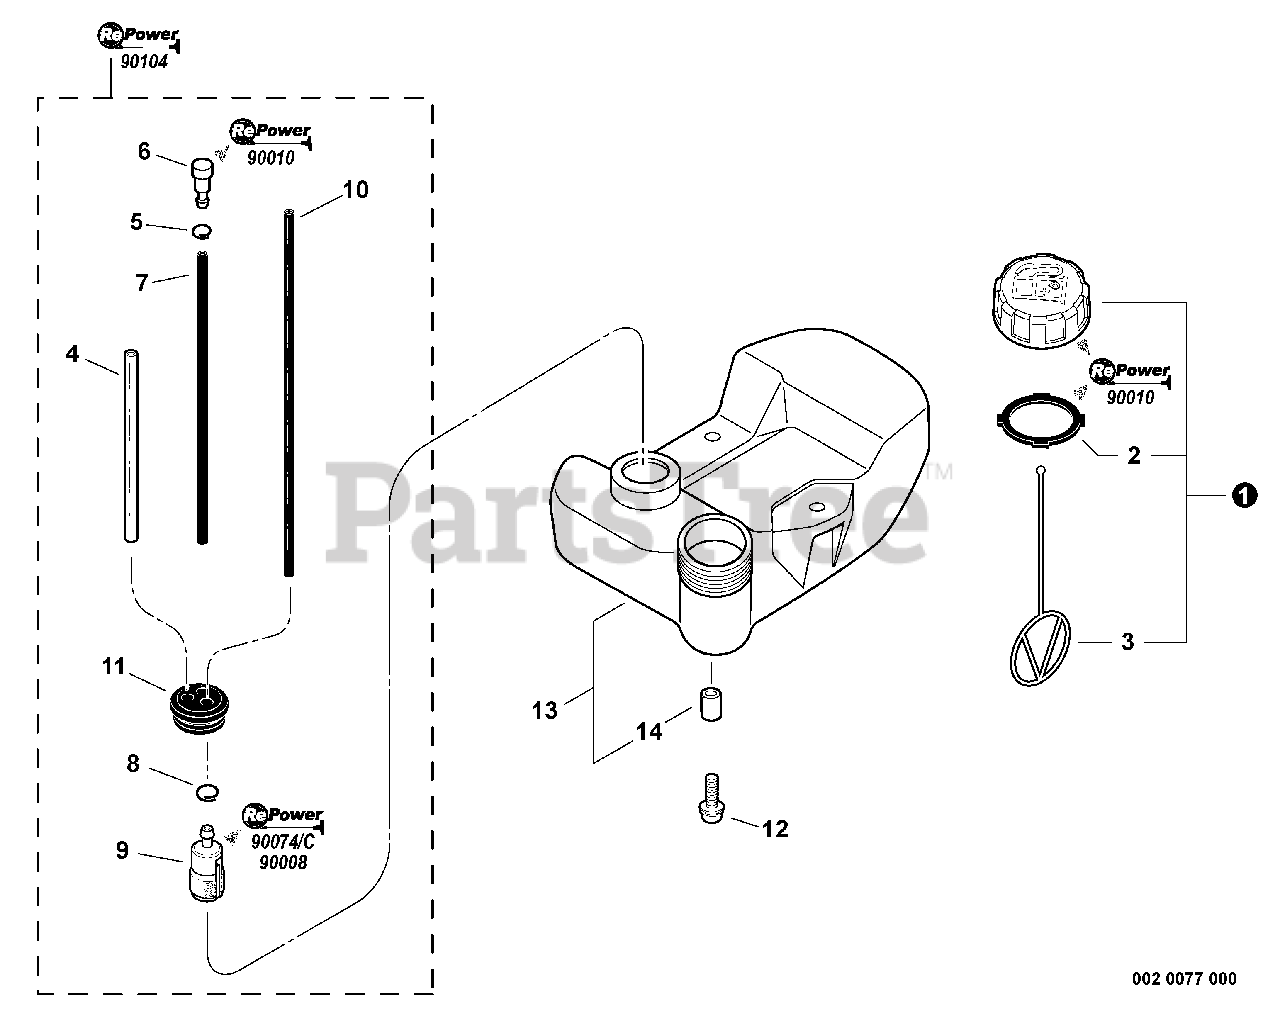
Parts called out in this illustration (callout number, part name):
1	CAP ASSY - ORANGE
2	GASKET, CAP
3	CONNECTOR, CAP
4	PIPE - 3X6X80 -- CLEAR
5	CLIP - 6.5
6	VENT, FUEL TANK
7	PIPE - 3X6X115 -- BLACK
8	CLIP - 6.5
9	FILTER, FUEL
10	PIPE - 3X6X170 -- BLACK
11	GROMMET
12	SCREW - 5X16
13	FUEL TANK ASSY
15	RePower FUEL SYSTEM KIT
16	RePower TUNE-UP KIT
17	RePower FILTER KIT
18	Repower CAP AND VENT KIT
